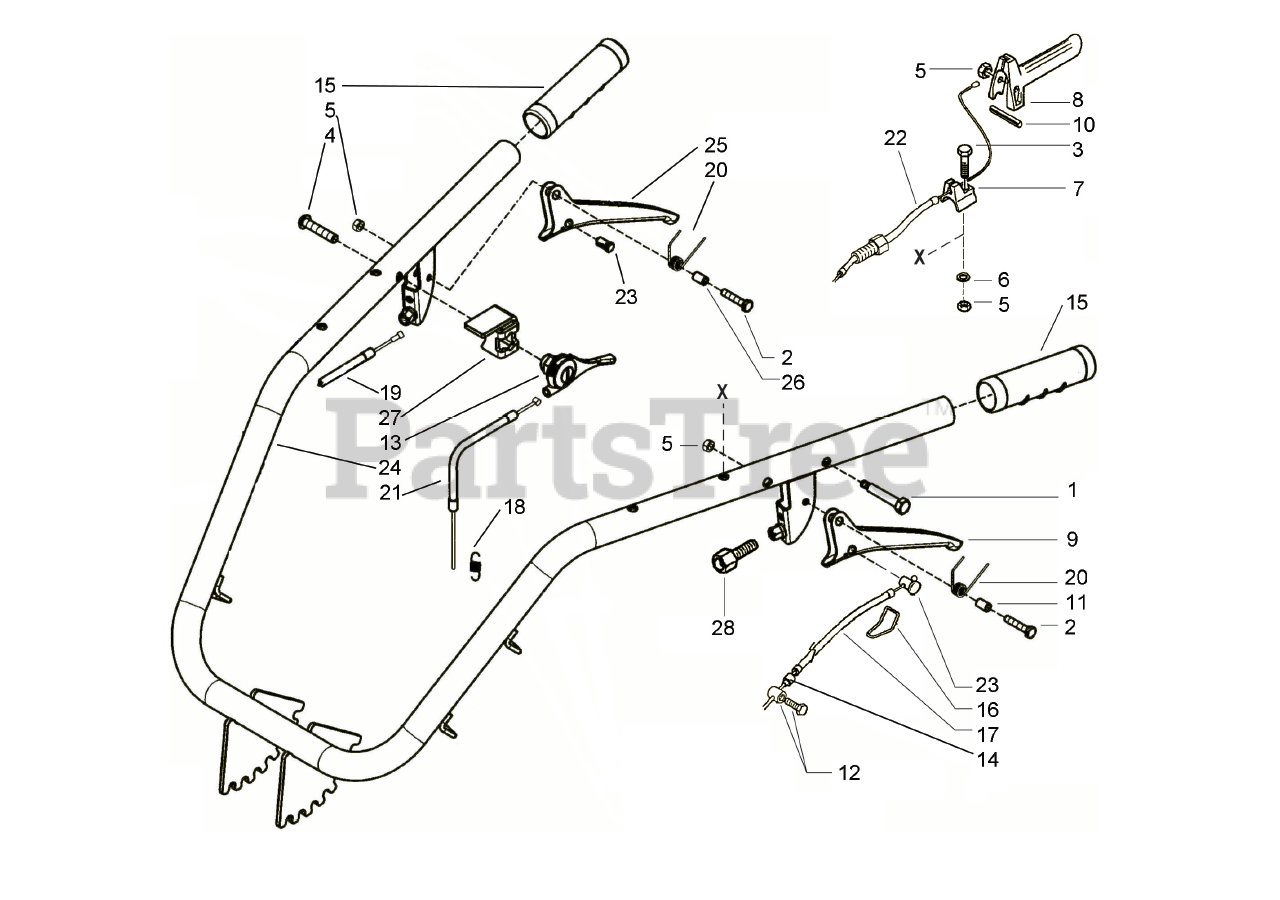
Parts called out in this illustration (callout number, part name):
1	CAP SCREW, M6 X 45
2	CAP SCREW, M6 X 25
3	CAP SCREW, M6 X 35
4	SCREW
5	LOCK NUT, M6
6	FLAT WASHER, M6
7	GUIDE, CABLE
8	LEVER, MOTOR STOP
9	LEVER, CLUTCH
11	LEVER, SPACER
12	CABLE CLAMP
13	LEVER. THROTTLE
14	SHEATH END
16	STOP WIRE
17	CABLE
18	SPRING
19	CABLE
20	SPRING
21	CABLE & SHEATH
22	CABLE, MOTOR STOP
23	BARREL
24	HANDLEBAR COMPLETE
26	SPACER
28	SCREW, ADJUSTING
